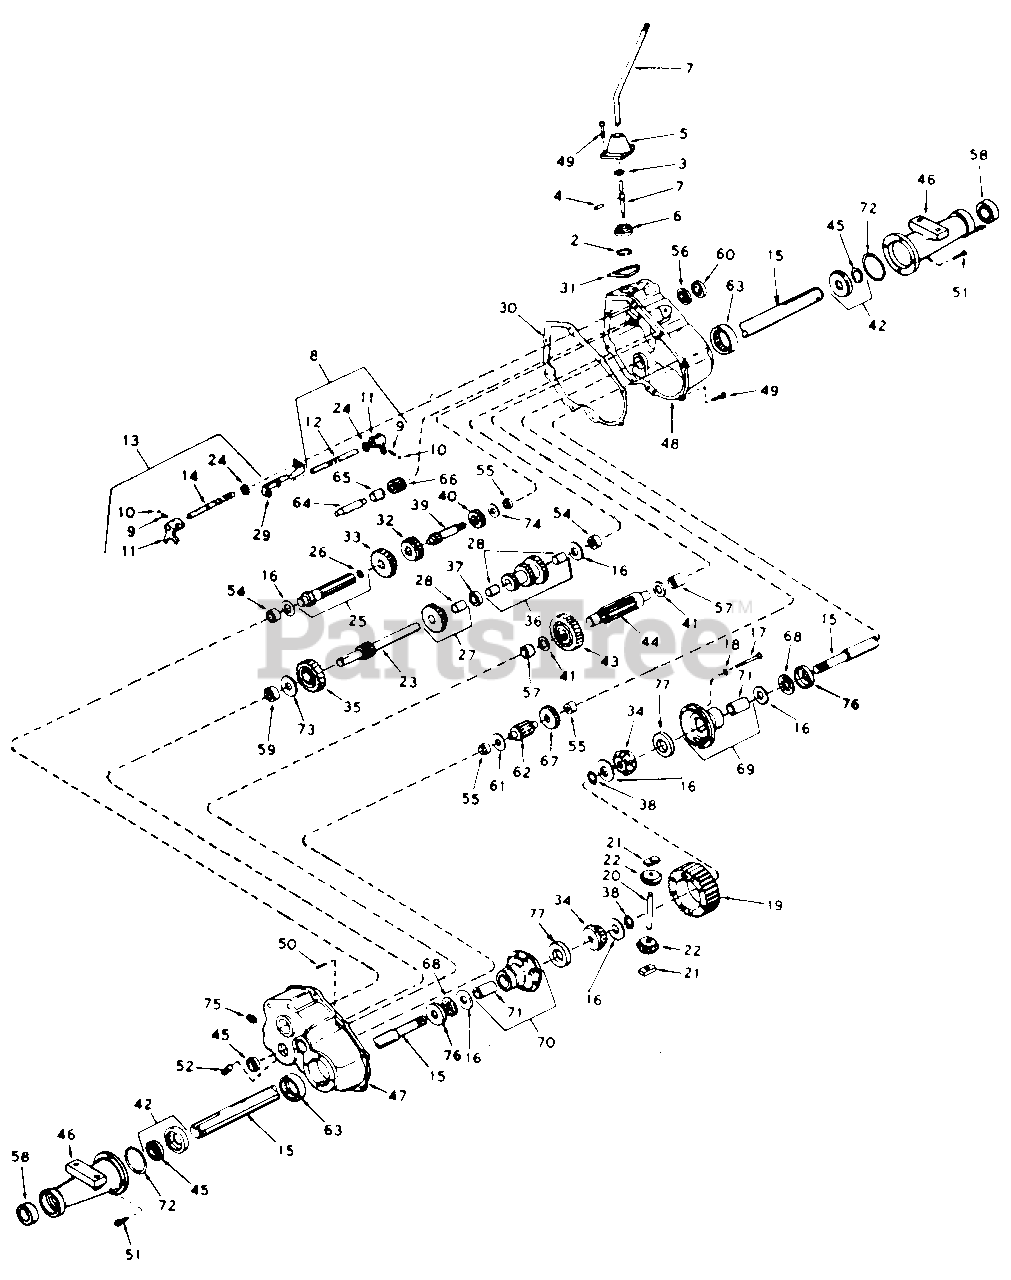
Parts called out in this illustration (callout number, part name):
2	Ring, Snap
3	Ring, Quad
4	Pin, Roll
5	Housing, Shift Lever
6	Keeper, Shift Lever
7	Lever, Shift
8	Rod Ass'y., Shin
9	Spring. Shift Fork
10	Ball Steel
11	Fork, Shifter
12	Rod, Shifter
13	Rod Ass'y., Shift
14	Rod, Shifter
15	Axle (18-11/32' Long)
16	Washer, Thrust
17	Scr., Hex Hd., 1/4-20 x 2l/2
18	Lock Washer, Split 1/4 "
19	Gear, Ring
20	Pin, Drive
21	Block, Drive
22	Pinion, Bevel
23	Shaft and Gear, Brake
24	Ring, Snap
25	Shaft and Bearing Ass'y., Pinion
26	Bearing, Needle
27	Gear Cluster Ass'y.
28	Bushing
29	Stop, Shifter
30	Gasket, Case and Cover
31	Gasket, Shifter Lever Housing
32	Gear, Shifting
33	Gear, Shifting
34	Gear, Bevel
35	Gear, Idler
36	Gear Cluster Ass'y.
37	Spacer
38	Ring, Snap
39	Shaft, Input
40	Spur Gear, Input Shaft
41	Washer, Thrust
42	Seal and Retainer Ass'y.,Oil
43	Gear, Output
44	Pinion, Output
45	Seal, Oil
46	Housing, Axle
47	Cover Ass'y., Transaxle
48	Case Ass'y., Transaxle
49	Screw, Flanged Hex Hd. 1/4-20 x 3 /4
50	Pin, Dowel
51	Screw, Hex Hd. Sems, 5/16-18 x 1
52	Plug, Magnetic Drain
54	Bearing, Needle
55	Bearing, Needle
56	Bearing, Ball
57	Bearing, Needle
58	Bearing, Ball
59	Bearing, Needle
60	Seal, Oil
61	Washer
62	ShaR and Pinion
63	Bearing, Needle
64	Shaft, Reverse Idler
65	Spacer, Reverse Idler
66	Idler, Reverse
67	Spur Gear (22 Teeth)
68	Bearing, Thrust
69	Carrier Ass'y., Differential
70	Carrier Ass'y, Differential
71	Bushing
72	Seal, Square Cut
73	Washer, Thrust
74	Washer, Thrust
75	Plug, Pipe
76	Race, Thrust
77	Washer
